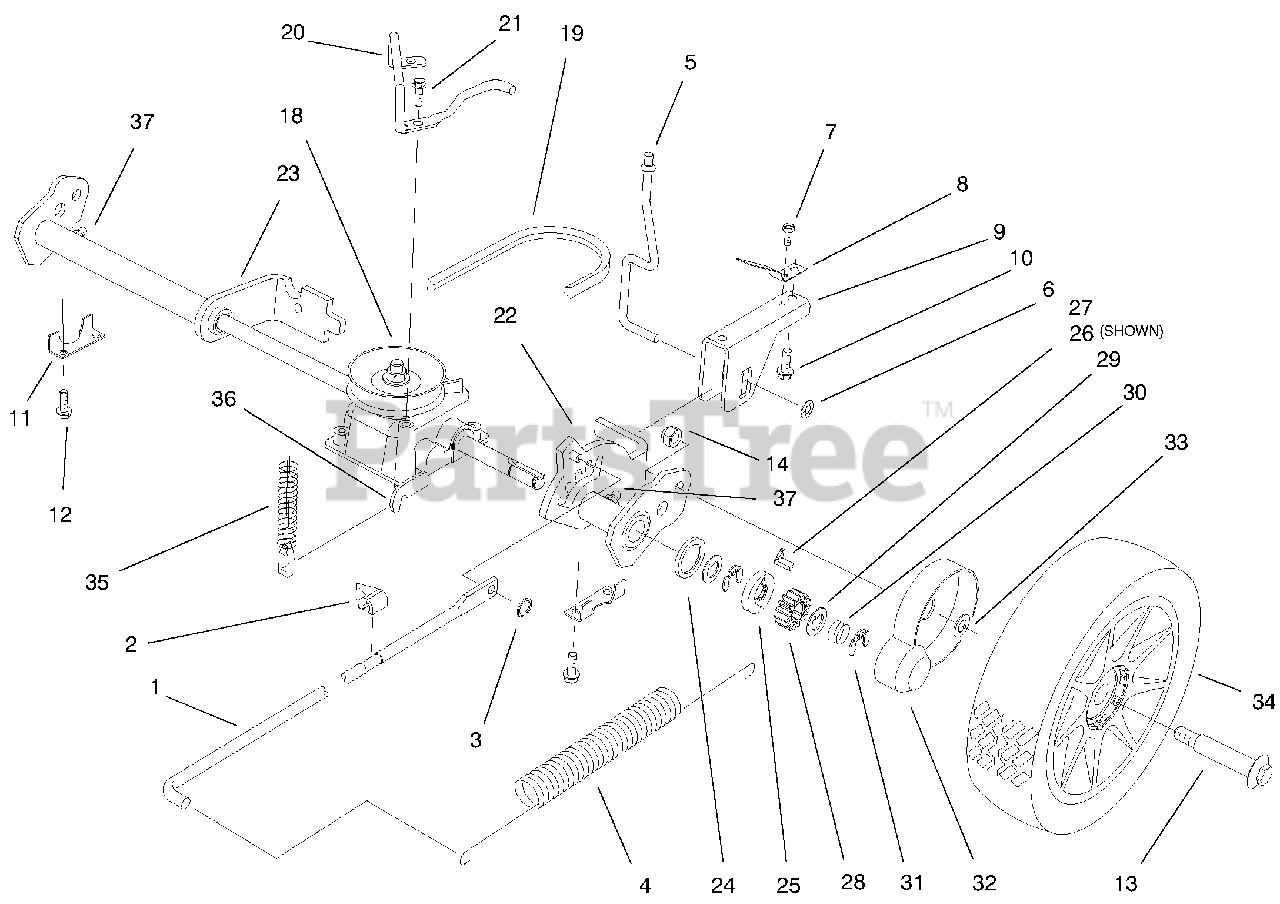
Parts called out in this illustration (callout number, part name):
1	ROD - LINK
2	INDICATOR-HEIGHT OF CUT
3	GRIP RING
4	SPRING-COUNTERBALANCE
5	TRIGGER ROD
7	SCREW 8 - 32 X 250
8	SPRING - TRIGGER RET
9	SADDLE - HOC
11	REAR SECURING PLATE
12	SCREW-HWH
13	BOLT-SHOULDER
14	NUT-LOCK, NI
18	GEAR CASE ASSY
20	Retainer Belt
21	SCREW-HWH
22	Arm-L.H. Pivot
23	RH PIVOT ARM ASSEMBLY
24	RING-FRICTION
25	WASHER-CLUTCH
26	KEY-ROCKING, LH
28	GEAR-PINION
29	WASHER-THRUST, KEYED
30	SPRING-COMPRESSION
31	RING-CLIP, LOCKING
32	COVER-WHEEL
33	SPACER-COVER, WHEEL
34	8" WHL ASM W/GEAR
35	SPRING-COMPRESSION
36	Bracket-Traction (Incl. with 71-9600)
37	FITTING-GREASE
